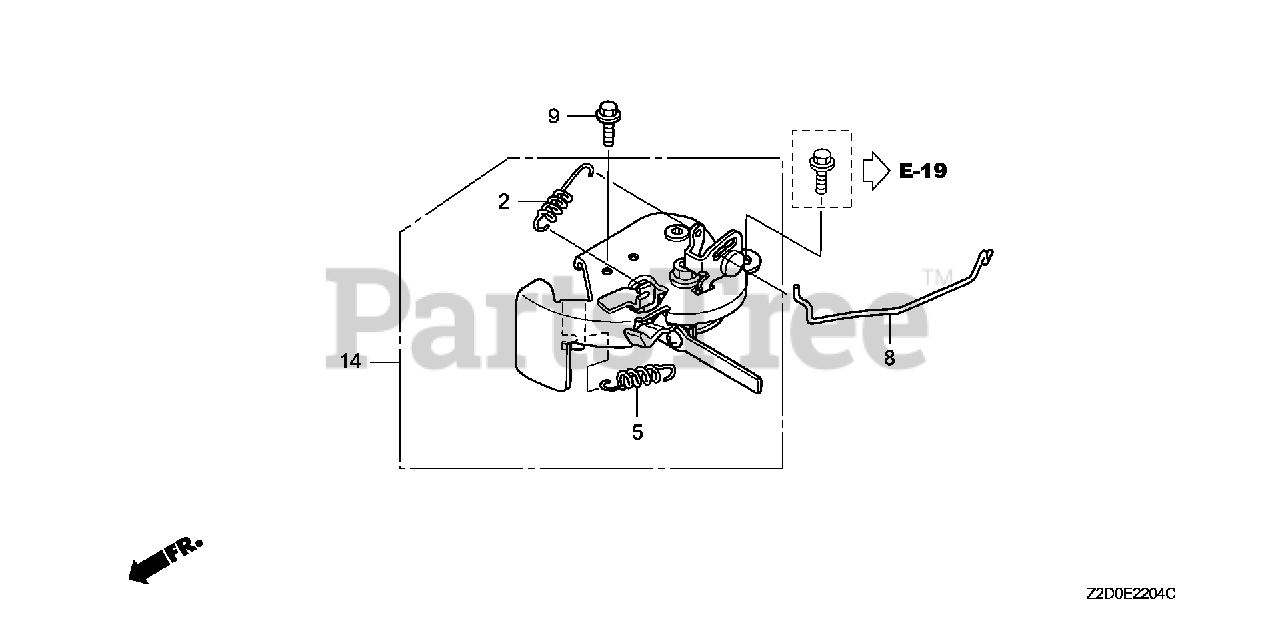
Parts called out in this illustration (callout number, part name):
2	SPRING, RETURN
5	SPRING, CHOKE LEVER
9	BOLT, FLANGE (6X16) (CT200)
14	LEVER ASSY., CHOKE
